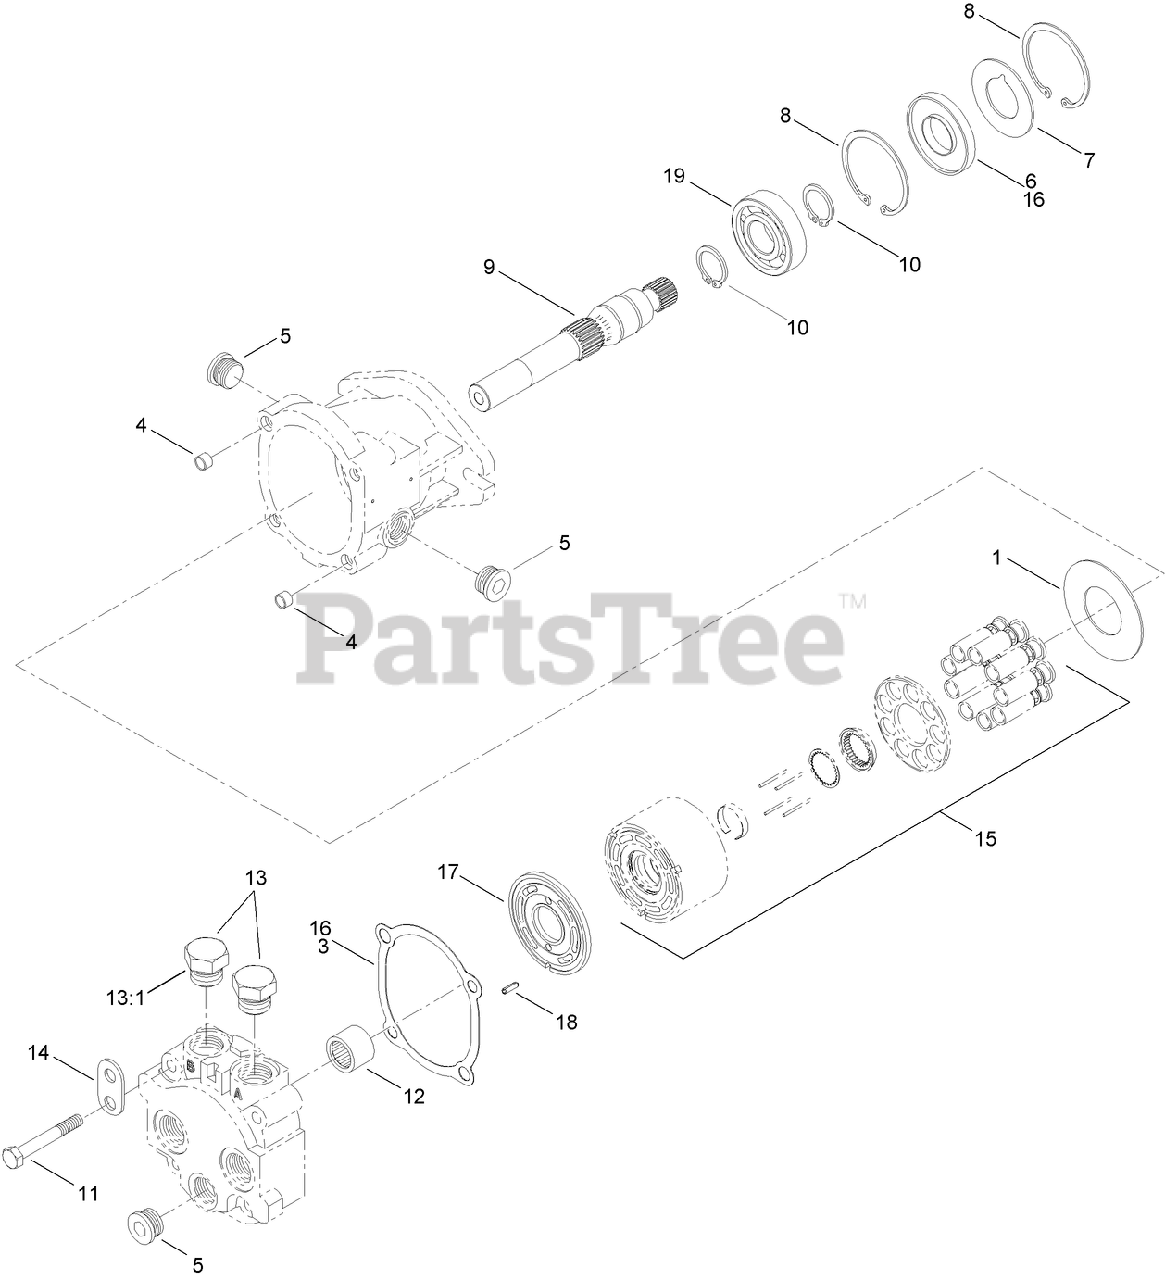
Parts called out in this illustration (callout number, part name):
1	PLATE-Thrust
3	GASKET-End Cap
4	PIN-Spring
5	PLUG ASM
6	SEAL-LIP
7	WASHER-BACKUP
8	RING-RETAINING
10	RING-RETAINING
11	SCREW-HH
12	BEARING-Needle
13:1	O-RING
14	BRACKET-Lifting
15	CYLINDER BLOCK KIT
16	KIT - SEAL OVERHAUL
17	PLATE-Valve
18	PIN-SLOTTED
19	BEARING-BALL
